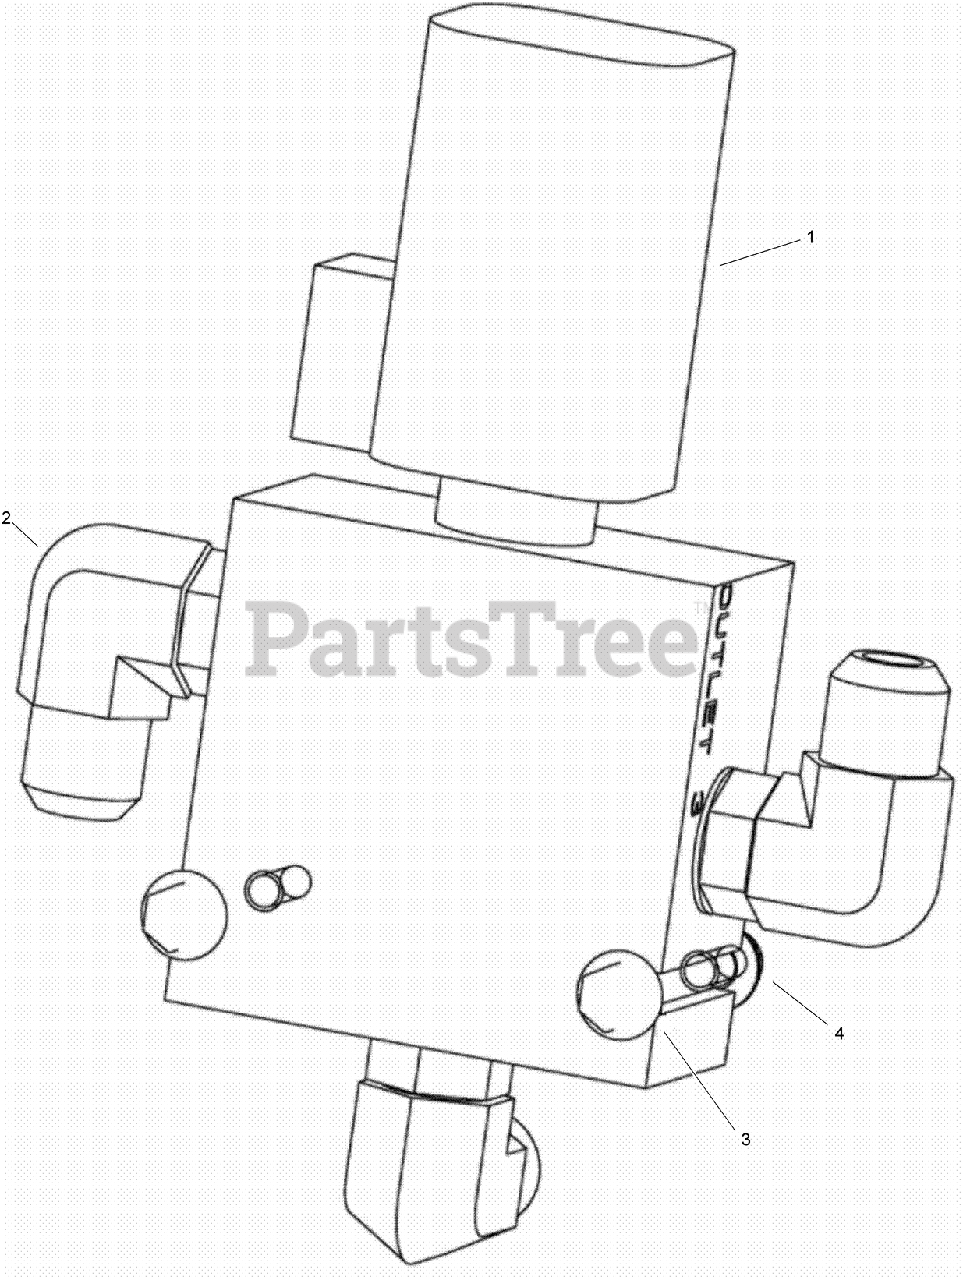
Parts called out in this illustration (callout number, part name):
1	DIRECTIONAL VALVE ASM
2	ELBOW-90 Adj 37FL 3/4 x 5/8 Tube
3	SCREW-FLANGE
4	NUT-TORQUE, PREVAILING
